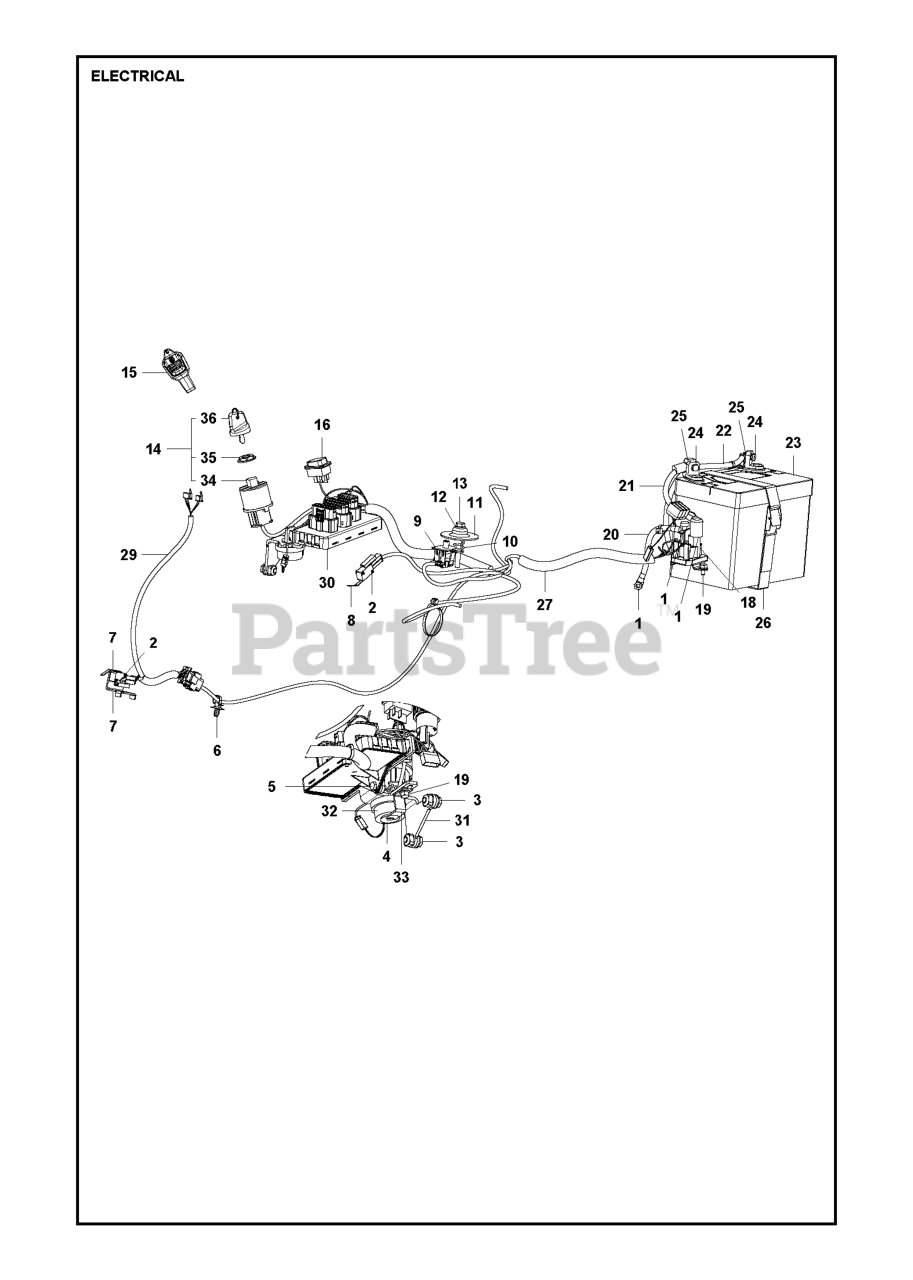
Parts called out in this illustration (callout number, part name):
5	SCREW
8	MICRO SWITCH
9	SWITCH SEAT, 4 PIN NC/NO
12	WASHER BRB 8.4X17
14	IGNITION SWITCH
24	SCREW EHHM
30	CONTROL.UNIT.RIDE.ON.IRIS.BASE
34	IGNITION SWITCH
36	IGNITION KEY
